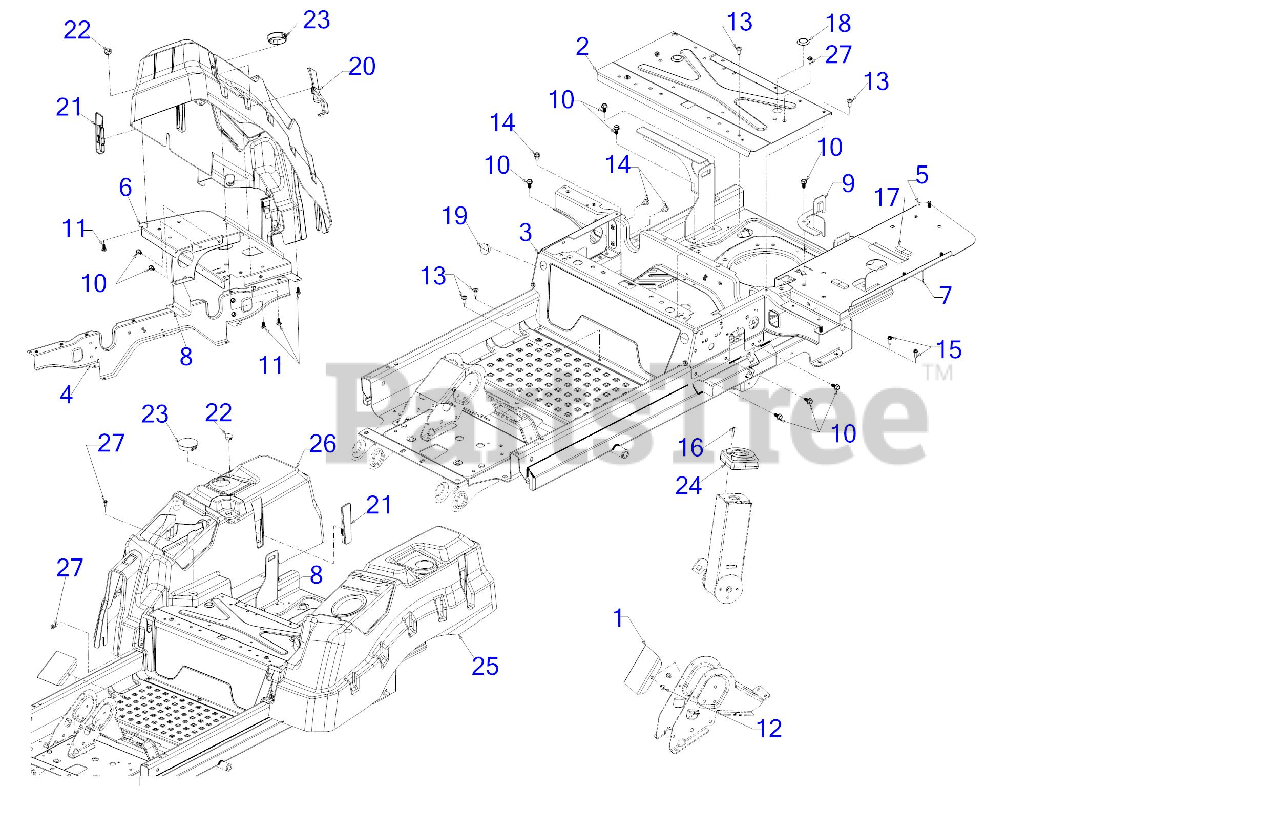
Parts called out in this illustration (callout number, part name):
10	SCREW 5/16-18 x .750
11	SCREW 5/16-14 x .750
12	SCREW 1/4-20 x .5
13	SCREW 5/16-18 x .750
14	SCREW 5/16-18 x .500
15	SCREW 1/4-20 x .750
16	SCREW #10-16 x 1.25
17	FOAM TAPE .625 WIDE x .25 THK BULK
19	PLASTIC PLUG
20	CONSOLE PLUG (RH) OUTER
21	CONSOLE PLUG (RH) INNER
22	CONSOLE PLUG (RH)
23	FUEL NECK PLUG
24	STEERING COLUMN COVER
25	CONSOLE (LH) 2.25" CAP
26	CONSOLE (RH) 2.25" CAP
27	SHOULDER SCREW M6-1 .368 X.115
